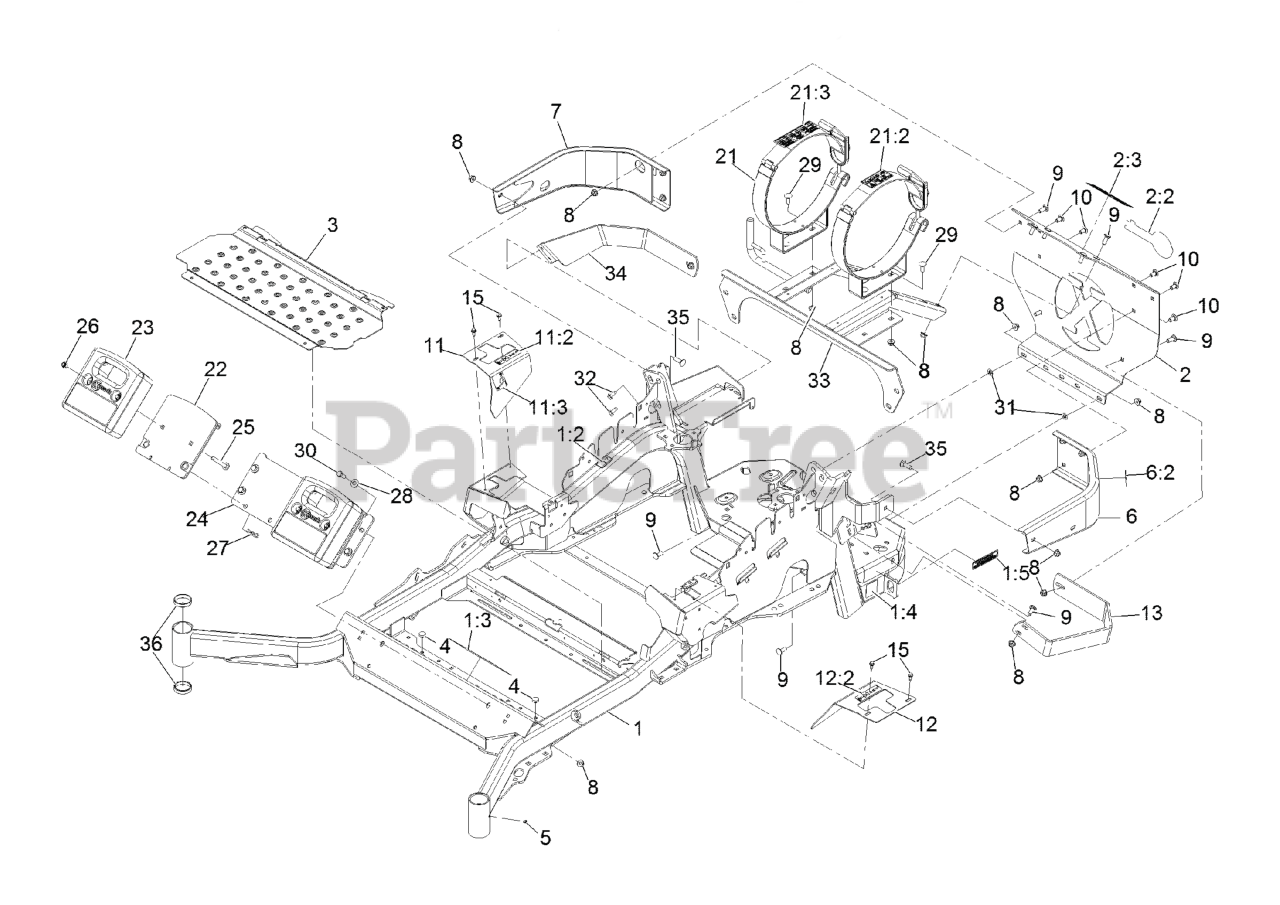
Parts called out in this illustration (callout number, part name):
1	MAINFRAME ASM
1:2	DECAL-WARNING
1:3	DECAL-DANGER
1:4	DECAL-HAZARD, PINCHED FINGER
1:5	DECAL-ARRESTOR, SPARK
2	REAR GUARD-LP W/DECALS
2:2	DECAL, EXMARK LOGO
2:3	Decal-LPG Fuel Tank Replacement
6	LH BUMPER ASM
6:2	DECAL-WARNING
7	BUMPER-RH
8	NUT-HF, NI
9	SCREW-CARR
10	SCREW-CARR
11	RH MOTION CONTROL COVER ASM
11:2	DECAL-CONTROL, MOTION
11:3	DECAL-PARK BRAKE, CE
12	LH MOTION CONTROL COVER ASM
12:2	DECAL-CONTROL, MOTION
13	GUARD-MUFFLER
15	SCREW-HWH
21	TANK BRACKET ASM (SET)
21:2	Decal-LPG Warning
21:3	Decal-LPG Tank Spec
22	WLD,WEIGHT MOUNT
23	WEIGHT,CAST 36LB
24	PLATE,WEIGHT ASM MOUNT
25	SCREW-CARR
26	NUT-LOCK, NI
27	PIN-HAIR
28	WASHER-BELLEVILLE
29	BOLT-CARR
30	SCREW-HH
31	NUT-PUSH
32	Screw-HWH 5/16-18 X 3/4 Tf
33	SUPPORT-TANK
34	STRAP-GUARD
35	BOLT-CARR
36	CUP-BEARING
